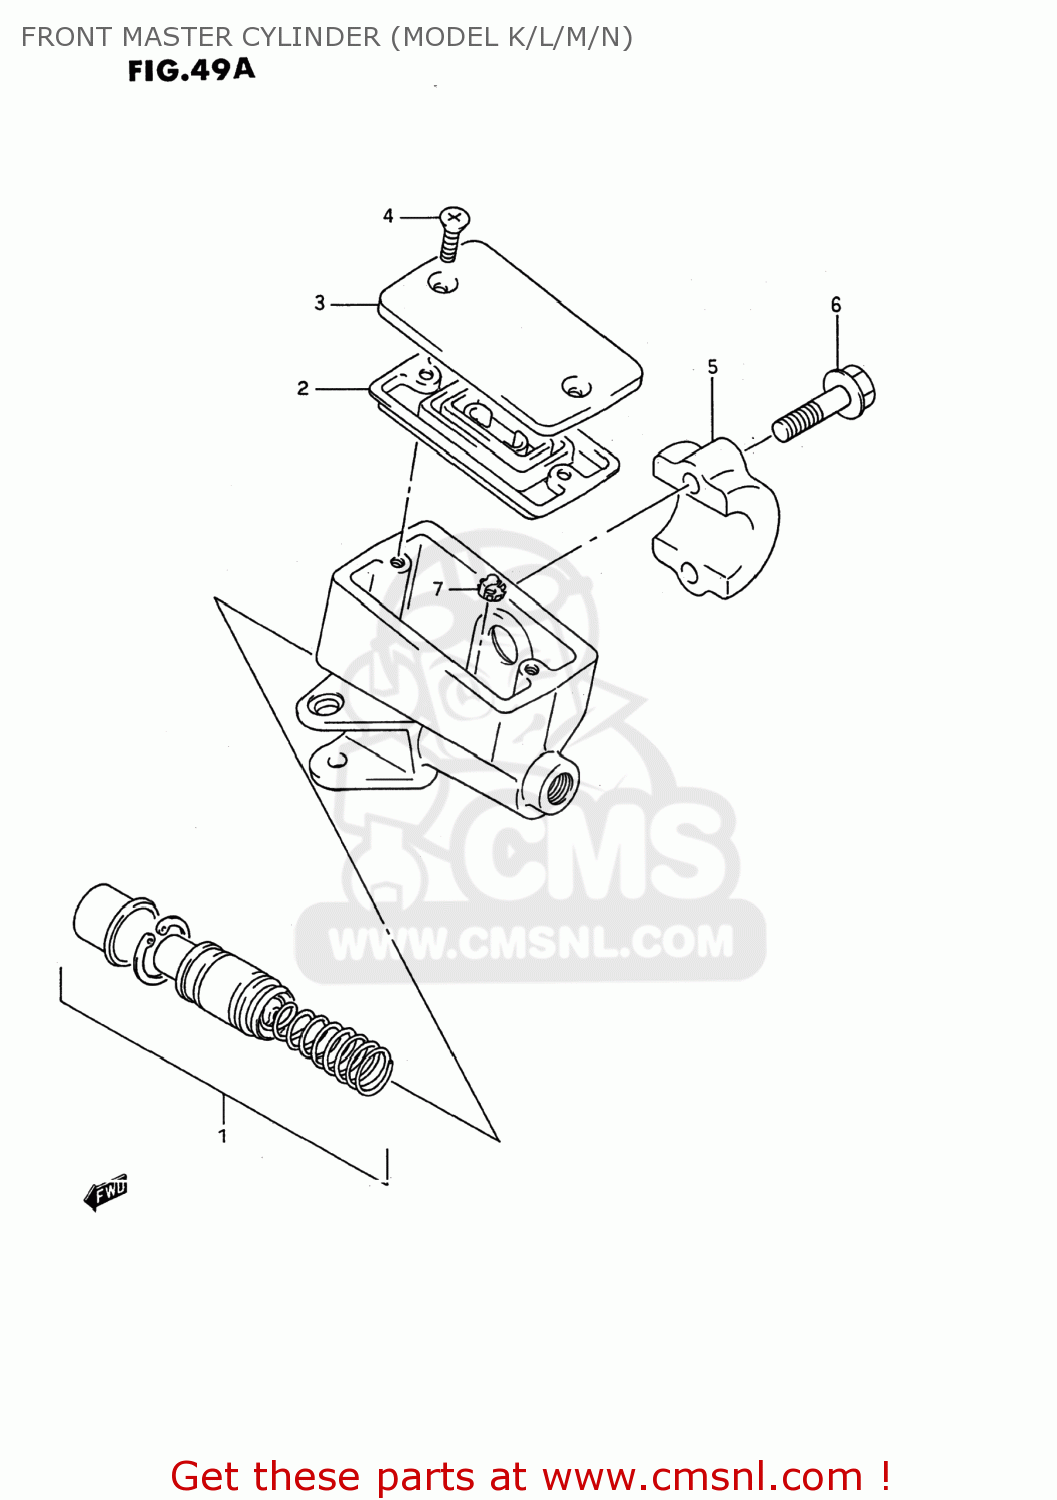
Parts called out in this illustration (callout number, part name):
1	PISTON & CUP SET
2	3
3	CAP
4	SCREW
5	HOLDER
6	BOLT(6X25)
7	PROTECTOR
